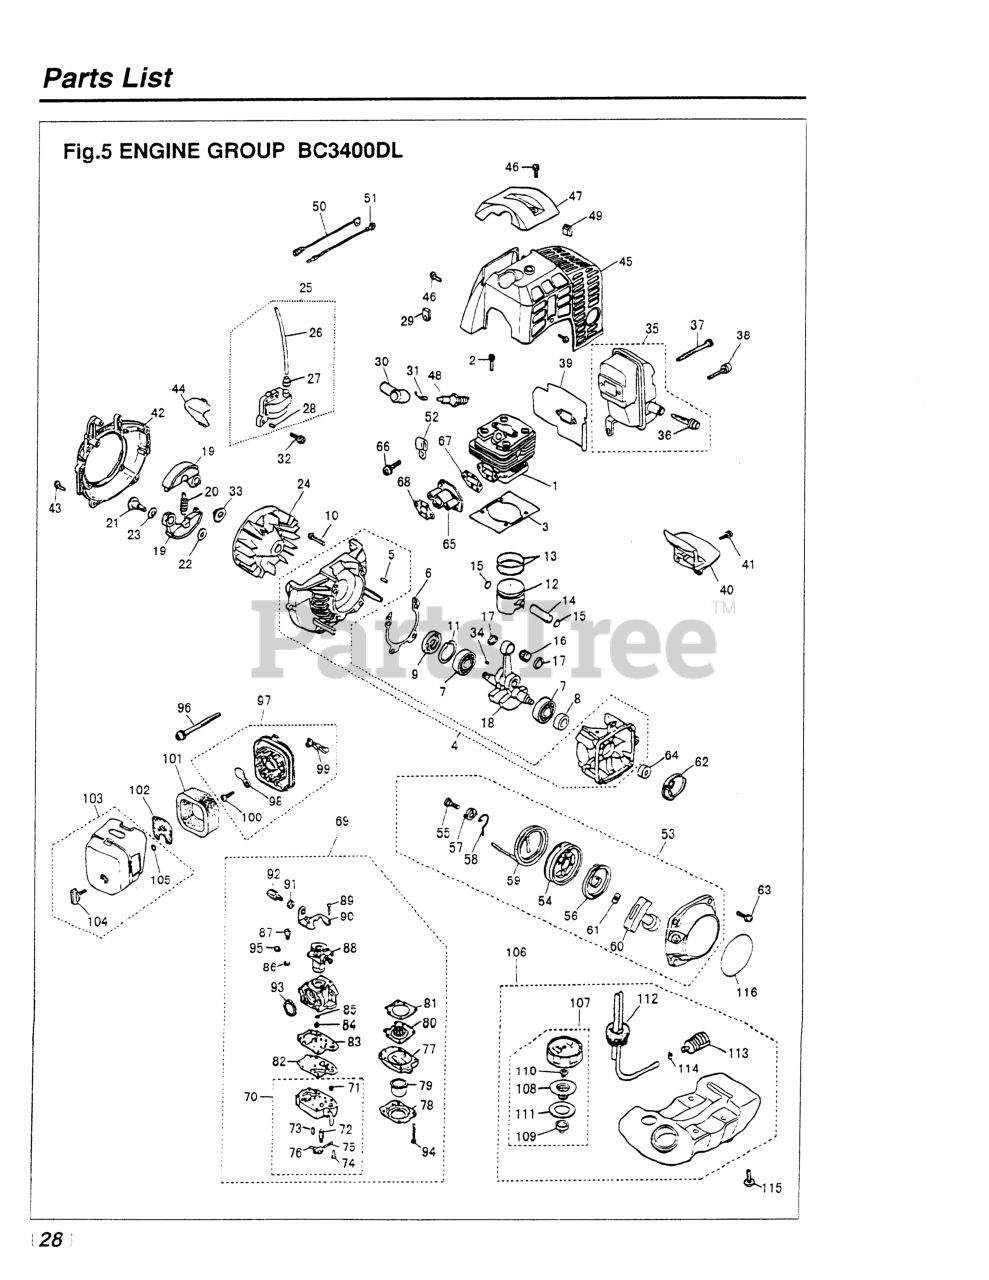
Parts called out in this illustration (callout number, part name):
1	CYLINDER
2	BOLT M5 x 20 (RPLS -12280)
3	GASKET, BASE
4	CRANKCASE COMPL (USE -21101)
5	PIN
6	GASKET
8	SEAL, OIL (RPLS 1100-21210)
9	SEAL, OIL (RPLS 1200-21220)
10	BOLT, M5 X 30
11	RING, SNAP, M32 x 1.2
12	PISTON
13	RING, PISTON
14	PIN, PISTON
15	RING, SNAP
16	BEARING
17	WASHER
18	CRANKSHAFT COMPL
19	SHOE, CLUTCH (RPLS -51110)
20	SPRING
21	SCREW
22	WASHER
23	WASHER (RPLS. -51240)
24	ROTOR
25	COIL ASSEMBLY
29	GROMMET
31	SPRING
32	BOLT, M4 x 22
34	KEY
35	MUFFLER ASSEMBLY
36	ARRESTER (RPLS 5850-15140)
37	BOLT, M5 x 60
38	BOLT (REPLACES 01252-30514)
40	PLATE (USE-15221)
41	SCREW,M5 X 14 (RPLS 1400-15510
43	BOLT M5 x 20 (RPLS -12280)
45	COVER
46	SCREW M5 x 12
47	GUARD
50	CORD
51	CORD, EARTH
52	CLAMP
53	RECOIL ASSEMBLY
54	REEL
55	SCREW
56	SPRING, SPIRAL
57	COLLAR
58	ARM
59	ROPE (USE 4810-75160)
60	KNOB
61	PLATE, STOPPER
62	PULLEY
63	SCREW, M6 x 14
66	SCREW, M5 X 20 (USE 5516-85510
67	GASKET, INSULATOR
68	GASKET, CARBURETOR
69	CARBURETOR ASSEMBLY
70	BODY, PUMP
72	VALVE, INLET
73	SPRING, METERING LEVER
74	SCREW, METERING LEVER PIN
75	PIN, METERING LEVER
76	LEVER
77	BODY, PURGE
78	COVER, PUMP
79	PUMP, PRIMING
80	DIAPHRAGM (USE 4810-81260)
81	GASKET, DIAPHRAGM
82	DIAPHRAGM
83	GASKET, PUMP
84	JET
85	RING, O
86	RING
87	SWIVEL
88	VALVE ASSY
89	SCREW
91	NUT, CABLE ADJUSTER
92	SCREW, CABLE ADJUSTER
93	RING, PACKING
94	SCREW
95	WASHER
97	BODY ASSEMBLY
98	PLATE, CHOKE
99	LEVER, CHOKE
100	SCREW (REPLACES 50030272)
101	ELEMENT
102	SCREEN
104	KNOB (RPLS -82220)
105	RING
108	HOLDER (USE -85300)
109	HOLDER, CAP
110	VALVE (NLA WHEN OUT)
111	PACKING
112	PIPE COMPLETE
113	FILTER ASSY
114	CLIP (REPLACES 2841-31280)
115	SCREW, M5 X 22
116	LABEL, RECOIL
